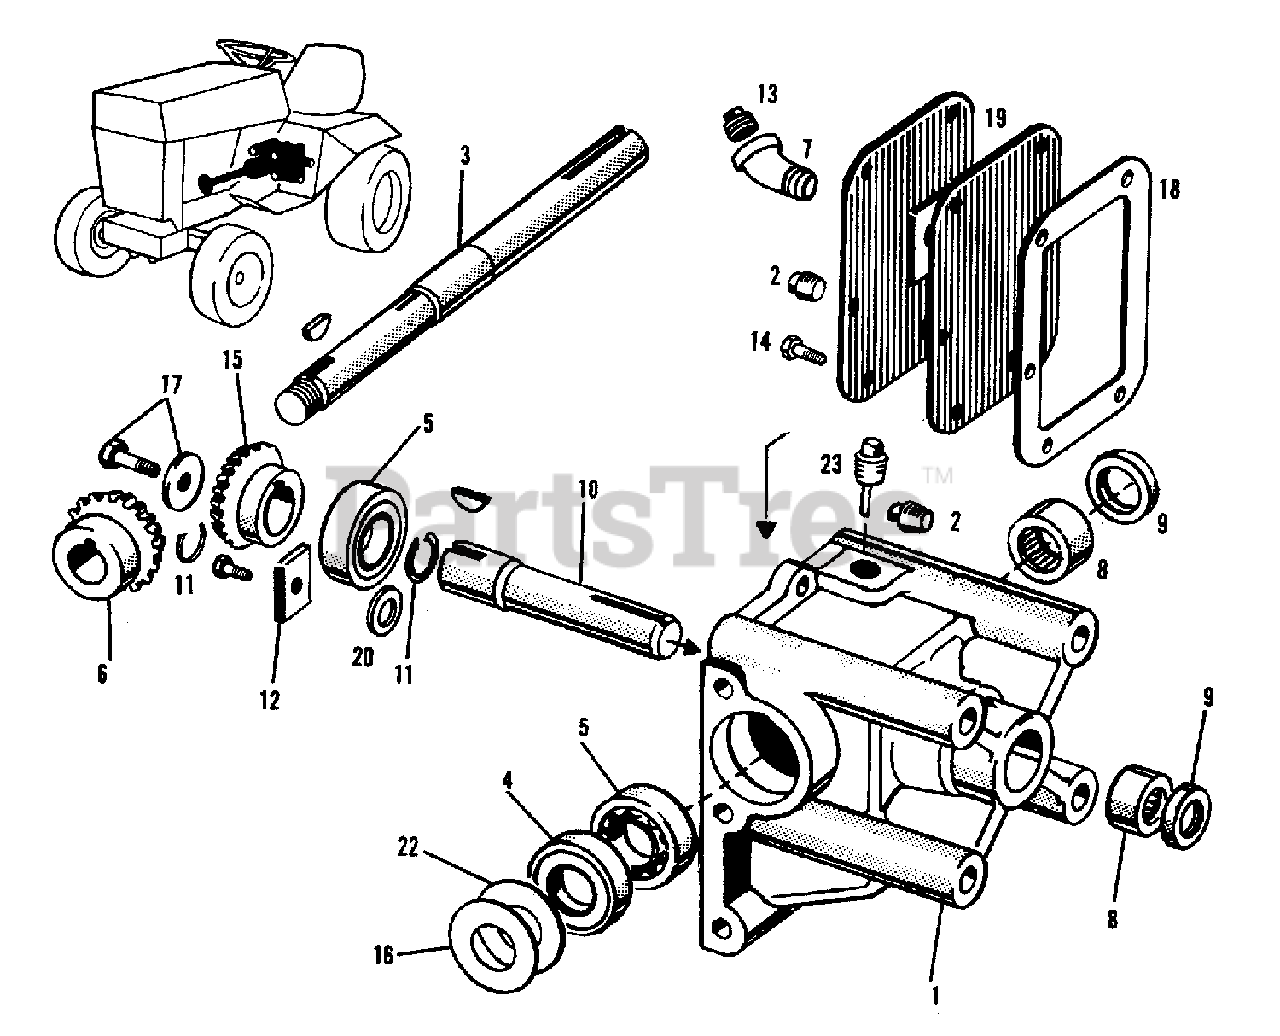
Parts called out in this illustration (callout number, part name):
1	HOUSING, Bevel Gear Box (For Tractor Prior S/N 25841001, 2604100, 26141001, & 29941001, Order Items 21, 22, 23)
2	PLUG, Pipe, 1/4 Standard (Square Head)
3	SHAFT, Driven
3	KEY, Hi-Pro, #606
4	SEAL, Oil
5	BEARING, Ball
6	GEAR, Bevel (Driven)
7	ELBOW, Street, 3/8 x 90 Degrees (Prior S/N 25841001, 26041001 &; 26141001 & 29941001)
8	BEARING, Needle
9	SEAL, Oil
10	SHAFT, Driven
10	KEY, Woodruff, 3/16 x 3/4
11	RING, Retaining
12	PLATE, Bearing Clamping
12	CAPSCREW, 5/16NC x 5/8
12	LOCKWASHER, 5/16
13	PLUG, Pipe, 3/8 Standard (Square Head)(Prior S/N 25841001, 26061001, 26141001, & 29941001)
14	CAPSCREW, 1/4NC x 5/8 (w/Intermediate Tooth Washer)
15	GEAR, Bevel (Driven)
16	SHIM, Inner (Use As Required)
17	CAPSCREW, 5/16NC x 3/4, Gr8
19	COVER, Housing (Prior S/N 25841001, 26041001, 26141001, & 29941001)
19	COVER, Housing (Eff. S/N 25841001 & Up, 26041001 & Up, 26141001 & Up, & 29941001 & Up)
20	WASHER, 7/16, Standard
21	PLUG ASSEMBLY, Oil Fill
22	SHIM, Outer
23	PLUG, Vent (Eff. S/N 25841001 & Up, 26041001 & Up, 26141001 & Up, & 29941001 & Up)
